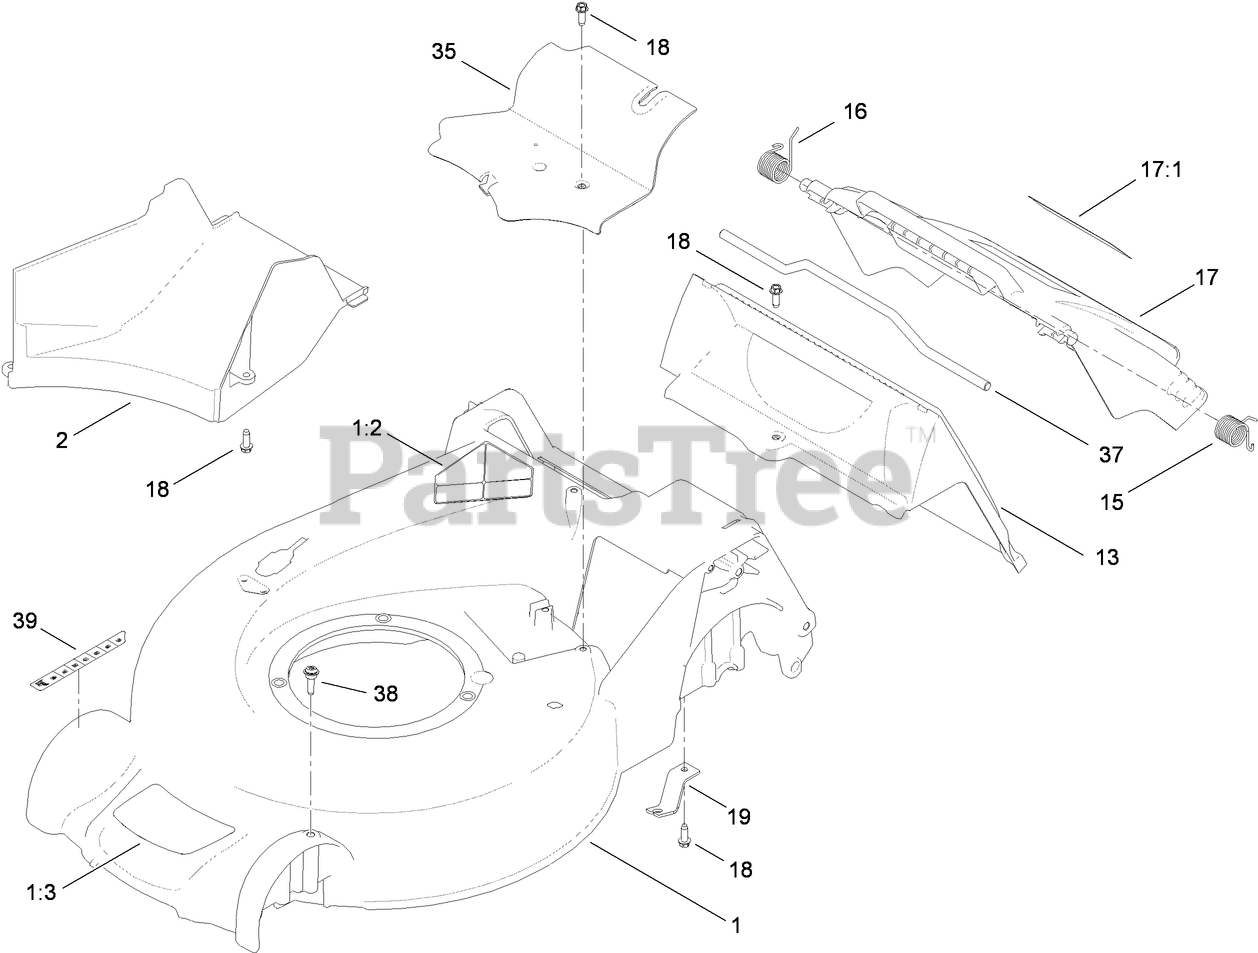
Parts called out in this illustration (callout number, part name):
1	HOUSING ASM
1:2	DECAL-DANGER
2	RAMP-DISCHARGE
15	SPRING-TORSION
16	SPRING-TORSION
17	REAR DOOR ASM
17:1	DECAL-WARNING
18	SCREW-HWHTF
19	BRACKET-CABLE, TRACTION
35	COVER-BELT
37	ROD-DEFLECTOR
38	SCREW-SHOULDER, BHTF
39	DECAL-HOC
